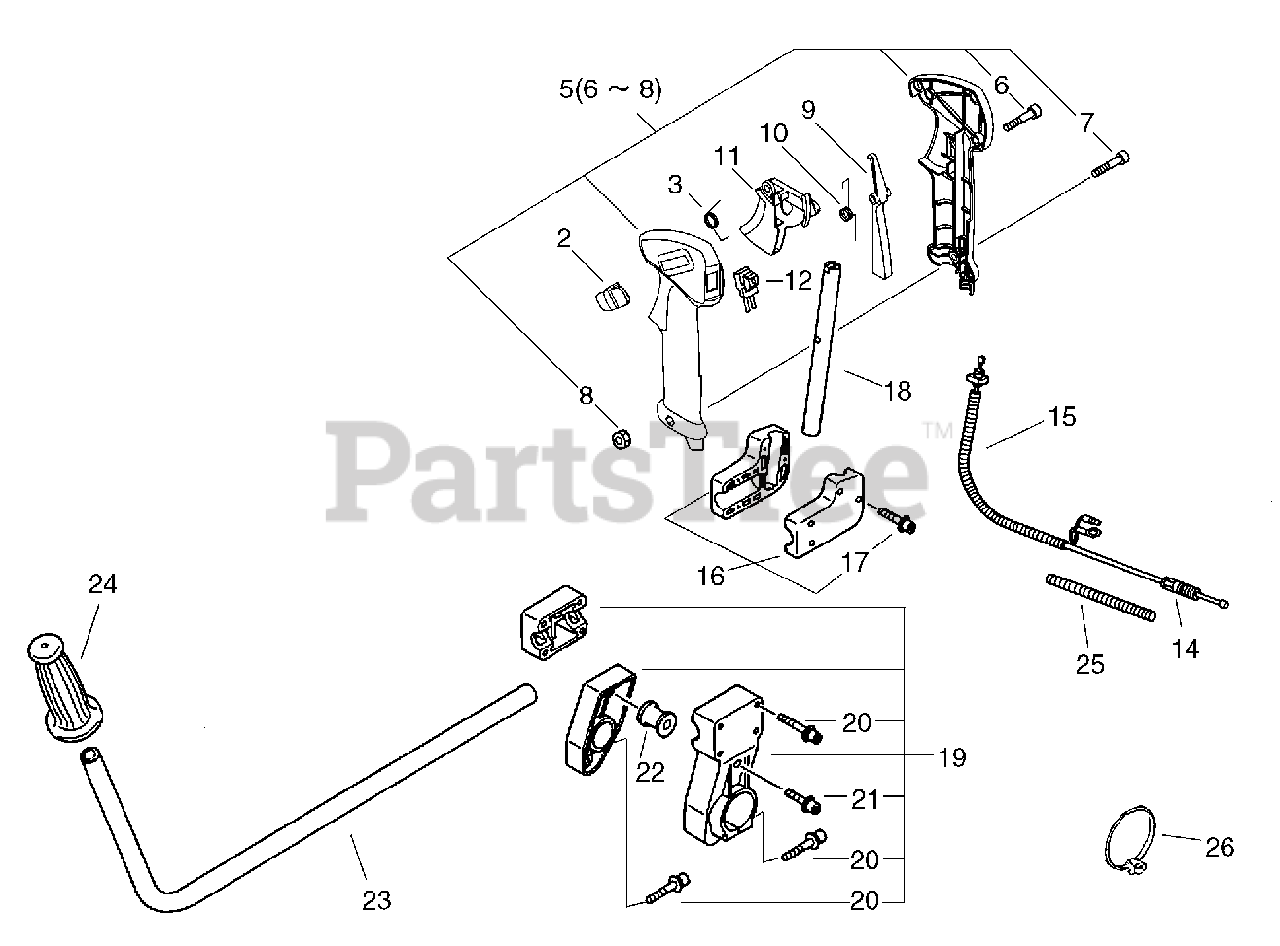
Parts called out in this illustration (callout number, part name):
2	LOCK, THROTTLE
3	SUPRING,TORSION
5	CONTROL HANDLE ASSY
6	SCREW - 4X16
7	SCREW - 5X30
9	LEVER, TRIGGER LOCKOUT
10	SPRING, LOCKOUT LEVER
11	TRIGGER, THROTTLE
12	SWITCH, IGNITION
14	CABLE, THROTTLE
15	TUBE, PROTECTIVE - CORRUGATED
16	BRACKET, HANDLE
17	SCREW - 5X25
18	HANDLE - RIGHT
19	BRACKET, HANDLE
20	SCREW - 5X35
21	SCREW - 5X14
23	HANDLE - FRONT
24	GRIP, HANDLE
25	TUBE, PROTECTIVE - CORRUGATED
26	CLAMP
